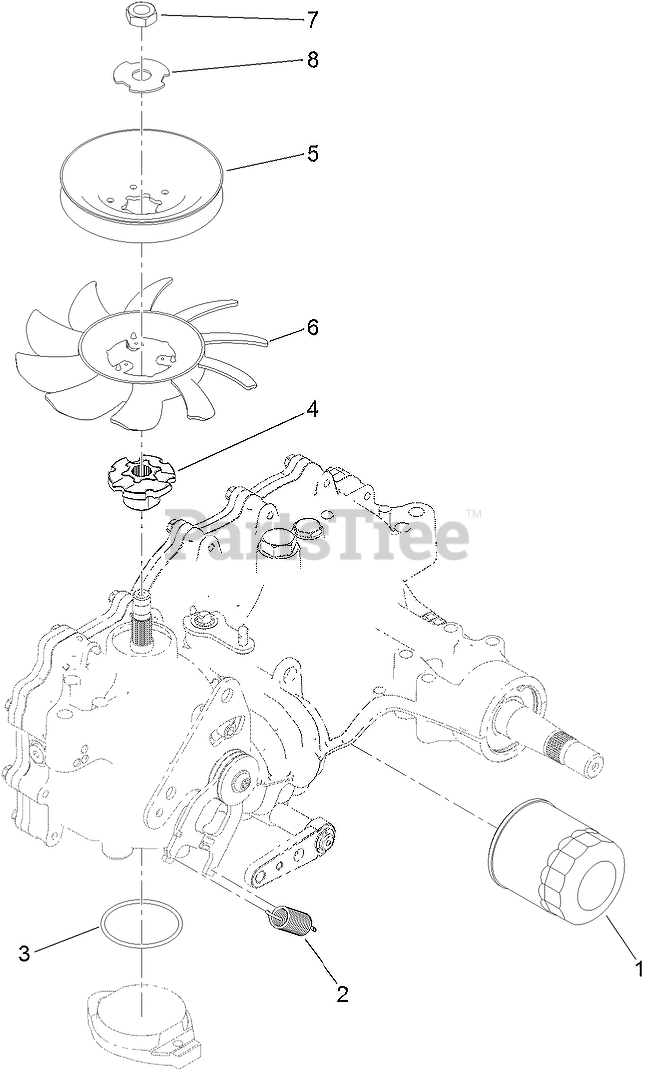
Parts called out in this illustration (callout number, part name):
1	ELEMENT-OIL FILTER, HYD
2	SPRING-EXTENSION
3	O RING-SEAL
4	HUB-PULLEY
8	WASHER-SLOTTED
99	BRAKE SHAFT SEAL KIT
